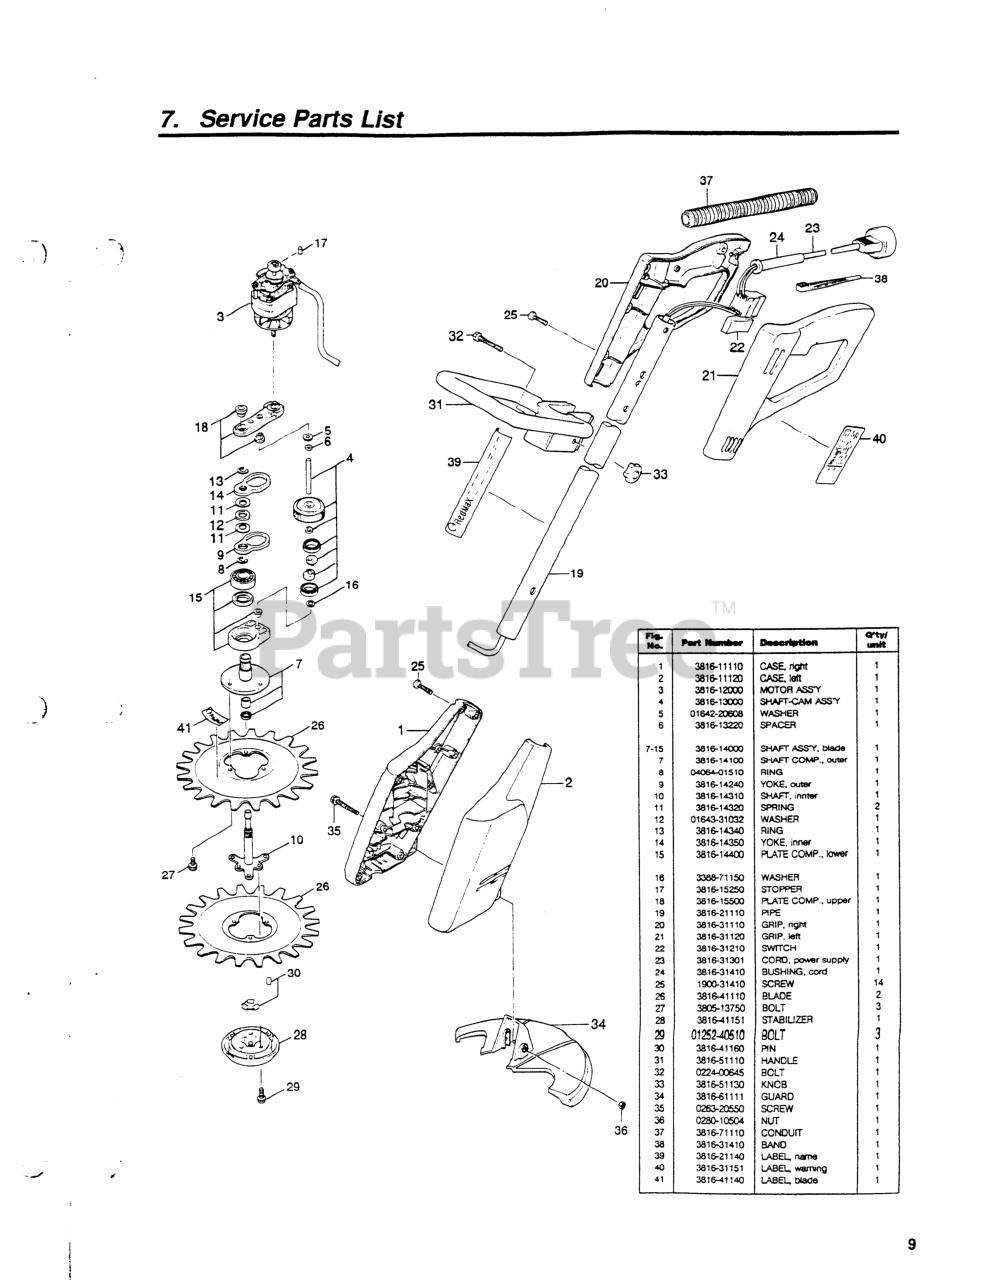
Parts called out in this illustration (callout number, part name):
1	CASE (R)
3	MOTOR ASSY.
4	SHAFT CAM ASSY
5	WASHER, M6 x .8
6	SPACER (NLA)
7	SHAFT COMP.,OUTER
8	RING, SNAP, M15 X 1.0
9	YOKE, OUTER
10	SHAFT, INNER
12	WASHER, M10 x 3.2
14	YOKE, INNER (NLA)
15	PLATE COMP., LOWER
18	PLATE COMP., UPPER
20	GRIP (R)
21	GRIP (L)
23	CORD (RPLS -31300) (NLA)
24	BUSHING, CORD
25	SCREW, HOUSING
27	BOLT
28	STABILIZER (RPLS -41150)
29	BOLT, M5 X 10
32	BOLT, M6 X 45
35	SCREW, M5 X 50
36	NUT, M5 X 4
38	BUSHING, CORD
40	LABEL, WARNING
NI	SHAFT ASSEMBLY
